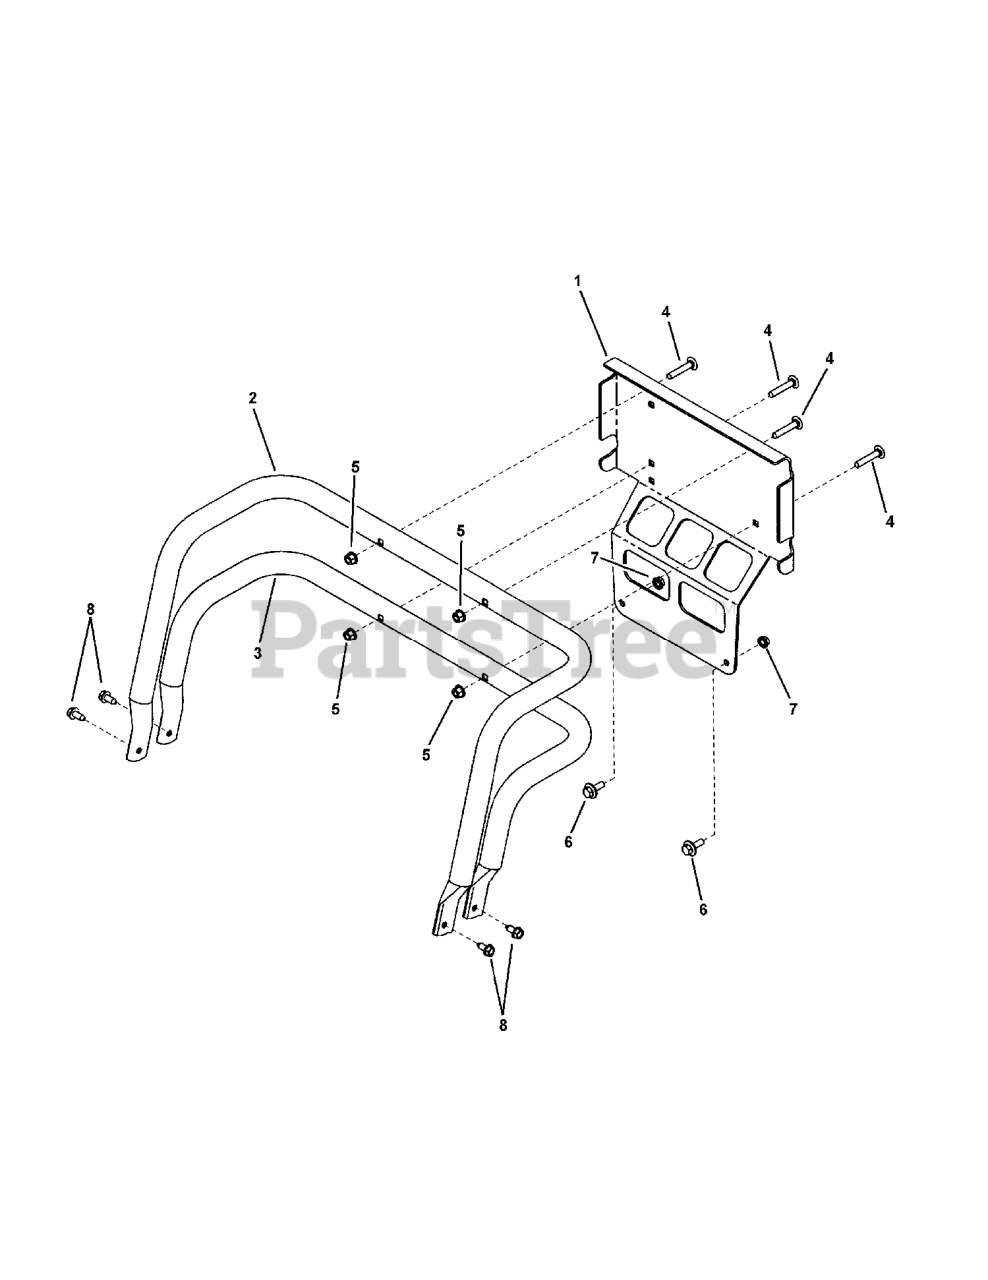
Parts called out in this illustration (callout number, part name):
1	PLATE, Brand
2	TUBE, Bumper, Upper
3	TUBE, Bumper, Lower
4	BOLT, 5/16-18 x 1-3/4" Round Head Short Square Neck
5	NUT, 5/16-18 Hex Flange Nyloc
6	BOLT, Shoulder
7	NUT, 5/16-18 Hex Flange Lock, Large, Black
8	SCREW, 5/16-18 x 3/4" Hex Washer Head Self-Tap, Black
